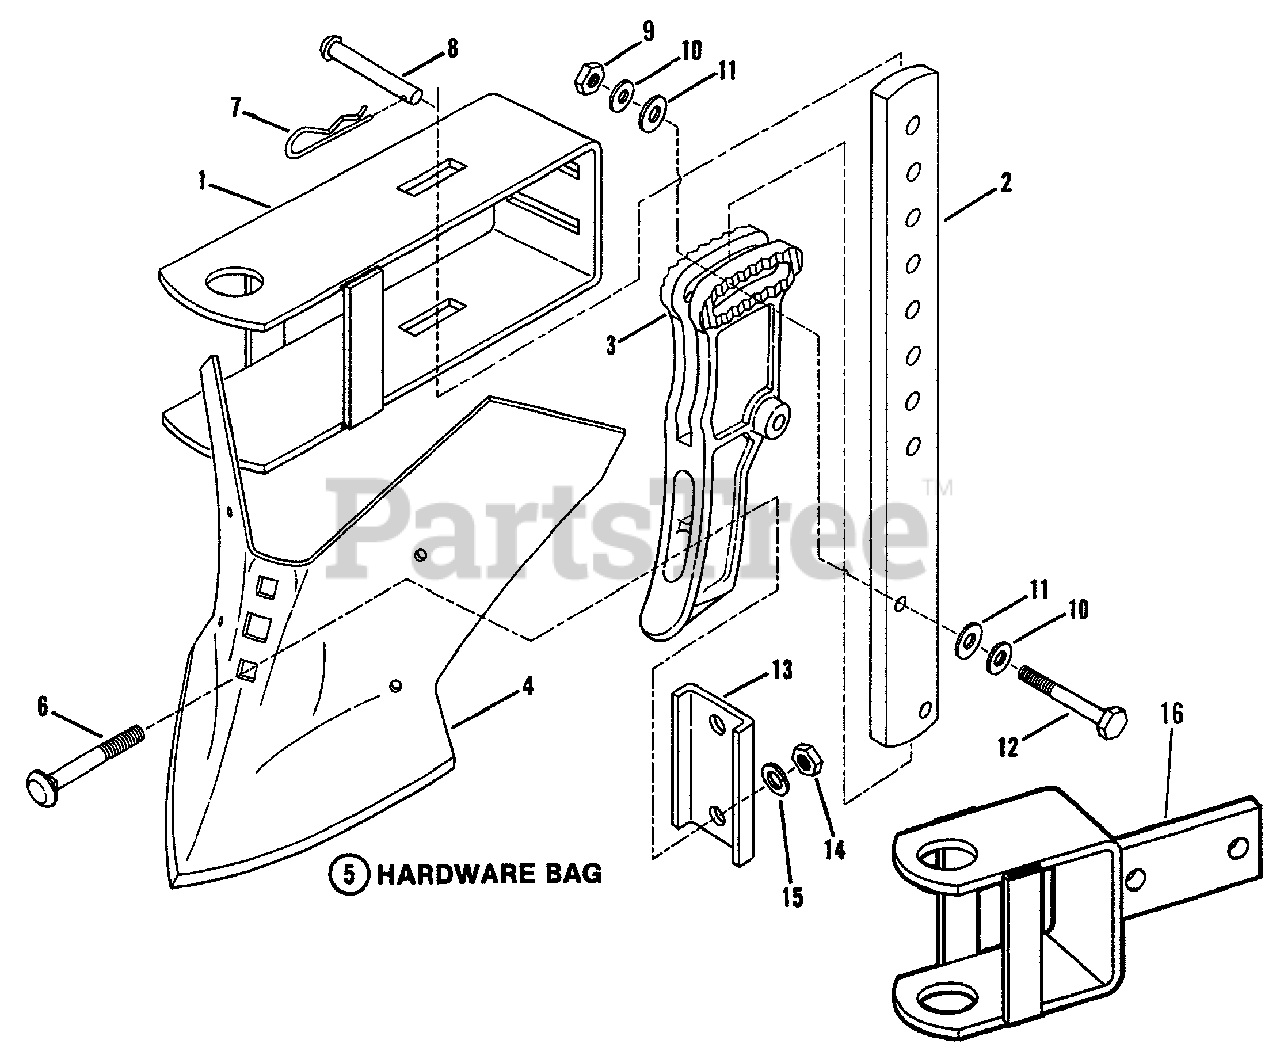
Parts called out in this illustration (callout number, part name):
1	YOKE ASSEMBLY
2	(NLA) PLOW BEAM
3	FOOT, Plow
4	(NLA) PLOW, 8" (Empire #E27-3)
5	(NLA) HARDWARE BAG for 60261
6	BOLT, 7/16-14 x 2-1/2 Square Neck Carriage, Gr. 2
7	PIN, Hair
8	PIN, 3/8 x 2-1/2" Clevis
9	NUT, 3/8-24 Hex, Grade 2
10	WASHER, 3/8" Flat
11	WASHER, 1/2" Flat
12	SCREW, 3/8-24 x 2-1/2" Hex Head Cap
13	(NLA) CLAMP
14	NUT, 7/16-14 Hex
15	WASHER, 7/16 Split Lock
16	(NLA) YOKE STRUCTURE
